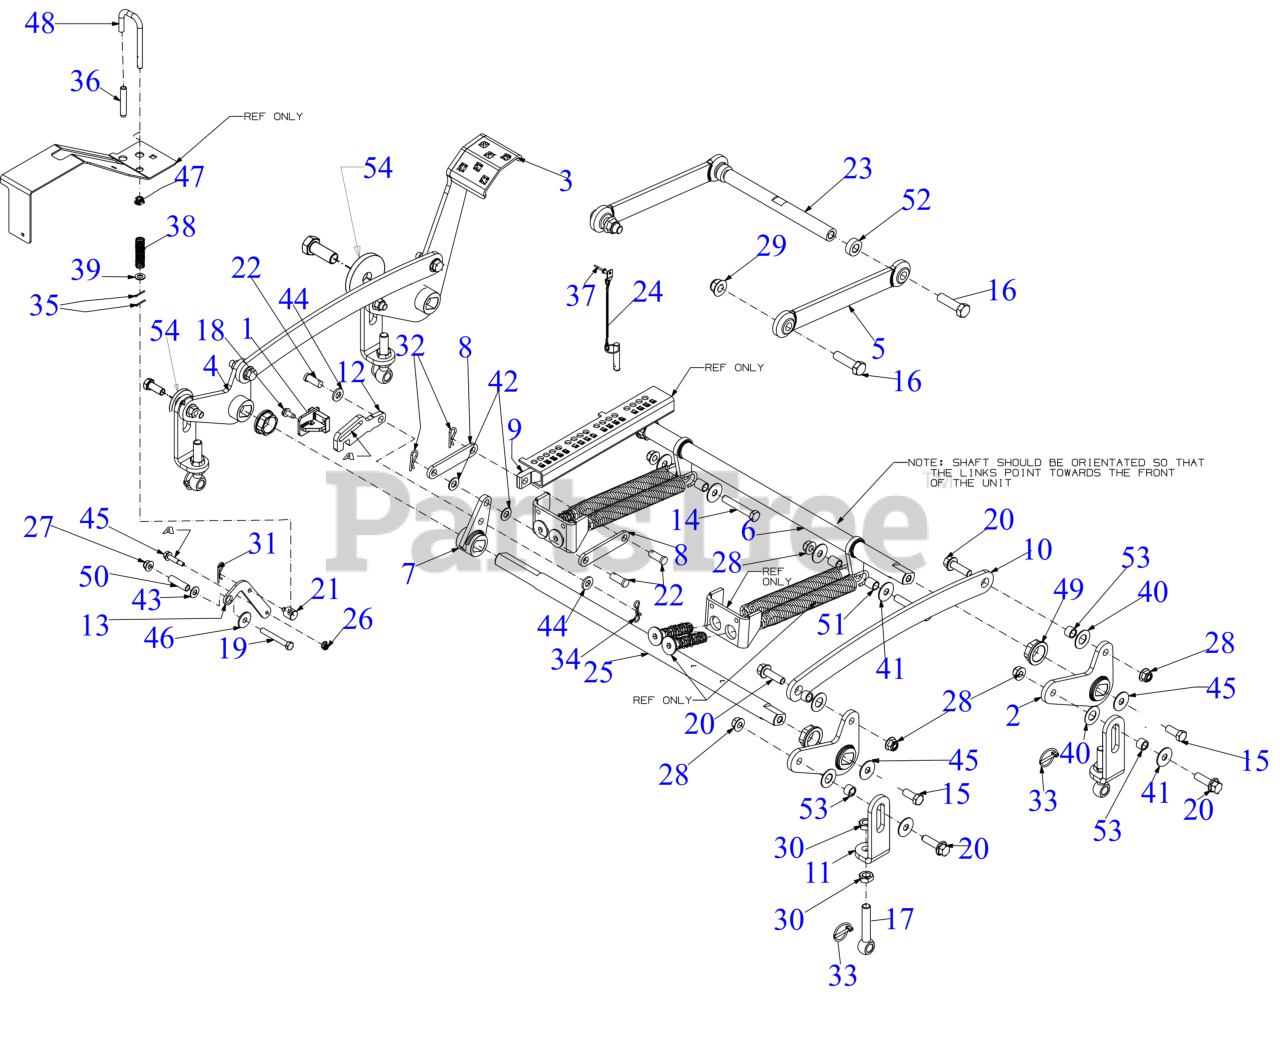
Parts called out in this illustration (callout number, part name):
1	LIFT LOCK MOUNT
6	FRONT DECK LIFT SHAFT
7	DECK LIFT HUB ASSEMBLY (LH)
8	DECK LIFT INDEX LINK
9	LIFT INDEX SLIDER ARM
13	PIVOT LOCKOUT LINK
14	SCREW-HEX 1/2-13 x 3.00
15	SCREW 1/2-13 x 1.25 GR5
16	SCREW 5/8-11 x 2.25 GR5
17	EYE BOLT 5/8-11 x 3.63
18	SCREW 5/16-18 x .750
19	SCREW 3/8-16 x 2.75 GR5
20	FLANGE BOLT 1/2-13:1.75:GR5
21	BRAKE ROD FERRULE
22	CLEVIS PIN .500 x 1.25
23	FRONT LIFT SHAFT
24	DETENT PIN
24	DECK LIFT KNOB
25	LIFT SHAFT 1.25 DIA
26	FLANGE LOCK NUT
29	FLANGE LOCK NUT
30	HEX JAM NUT
31	INTERNAL COTTER PIN
32	COTTER PIN
33	LYNCH PIN .1875
34	PIN:COTTER
35	COTTER PIN-3/32 DIA x .75
37	FULL TUBULAR RIVET
38	COMPRESSION SPRING .656 ODX 2.445"
39	FLAT WASHER
40	FLAT WASHER .760ID X1.49OD x .06
41	FLAT WASHER
42	FLAT WASHER .510X.995
43	FLAT WASHER.40 ID
44	FLAT WASHER
45	SHOULDER SCREW
46	SHOULDER SPACER
47	BUSHING .380 ID
48	DECK LOCK OUT ROD
49	FLANGE BEARING
51	SPACER 0.535 x 0.68 x 0.83
52	SPACER .635X1.25X.445
54	FLAT WASHER .53"x2.125"x.25"
